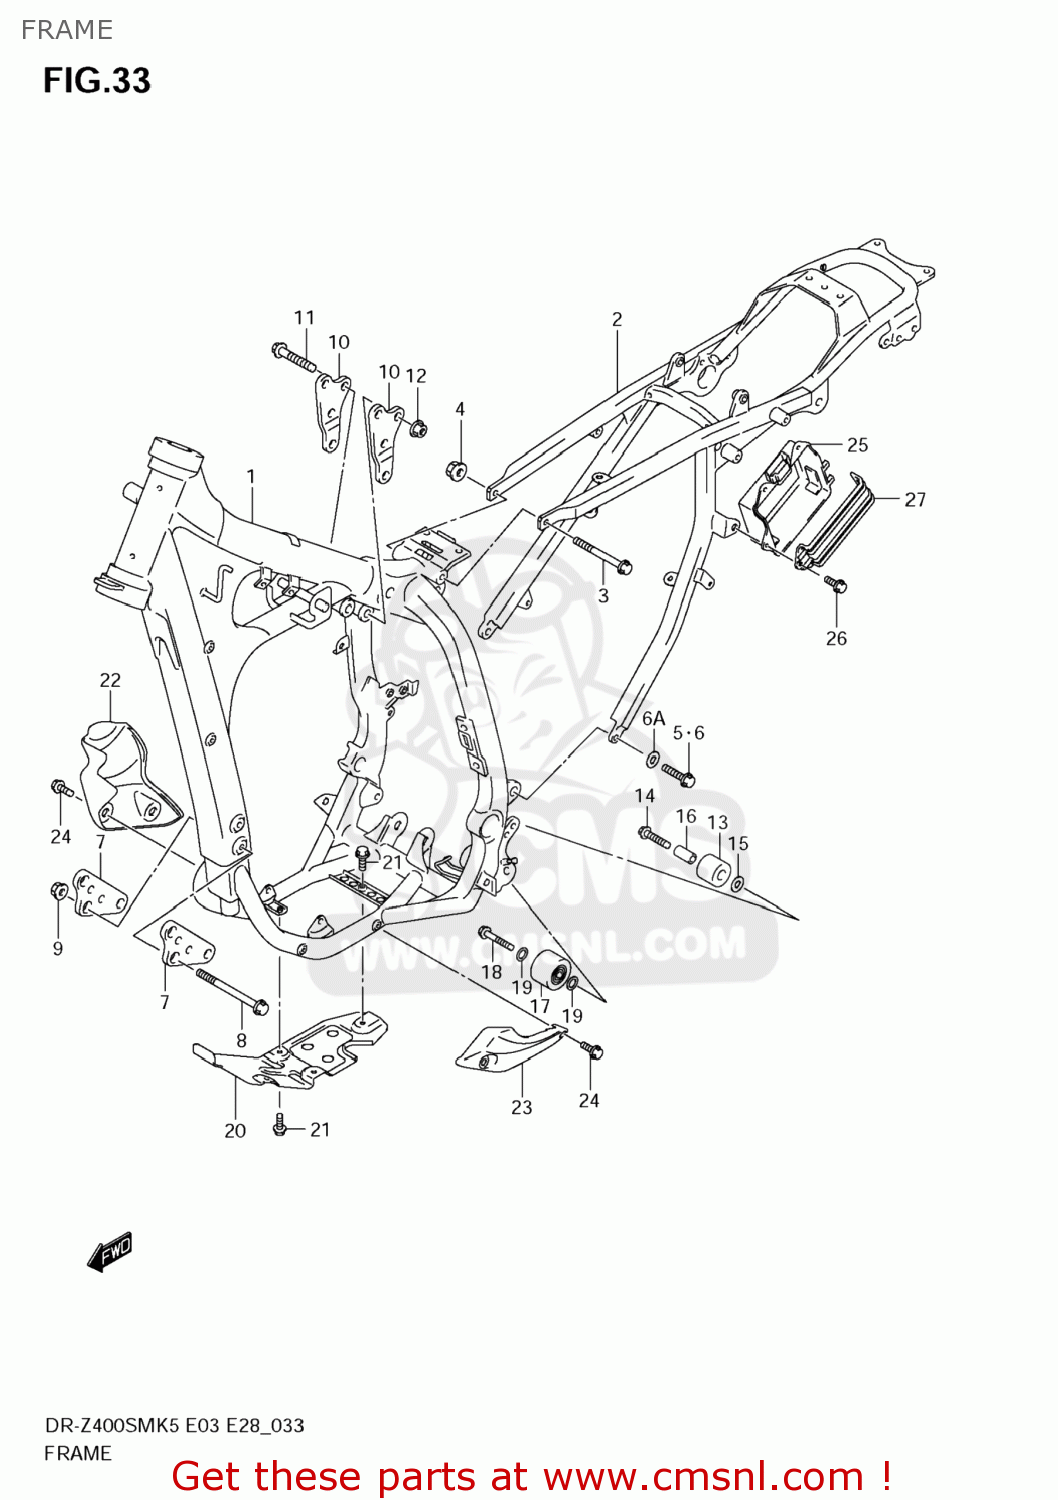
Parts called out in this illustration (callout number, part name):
1	FRAME (GRAY)
2	RAIL, SEAT
3	BOLT(8X115)
4	NUT
5	BOLT(8X16)
6	BOLT(8X20)
6A	WASHER(8.5X18X2)
7	PLATE,ENG MTG FR
8	BOLT(8X90)
9	NUT
10	PLATE,HEAD MTG RR
11	BOLT(8X50)
12	NUT
13	ROLLER,CHAIN CONTROL UPR
14	BOLT(8X41)
15	WASHER
16	SPACER(8.6X12.2X26.5)
17	ROLLER,CHAIN
18	BOLT(8X41)
19	SHIM(8X12X1)
20	PROTECTOR,ENGINE
21	BOLT
22	GUARD,WATER PUMP
23	GUARD,MAG COVER
24	BOLT(8X16.5)
25	HOLDER,BATTERY
26	BOLT(6X17.8)
27	BAND,BATTERY HOLDER
